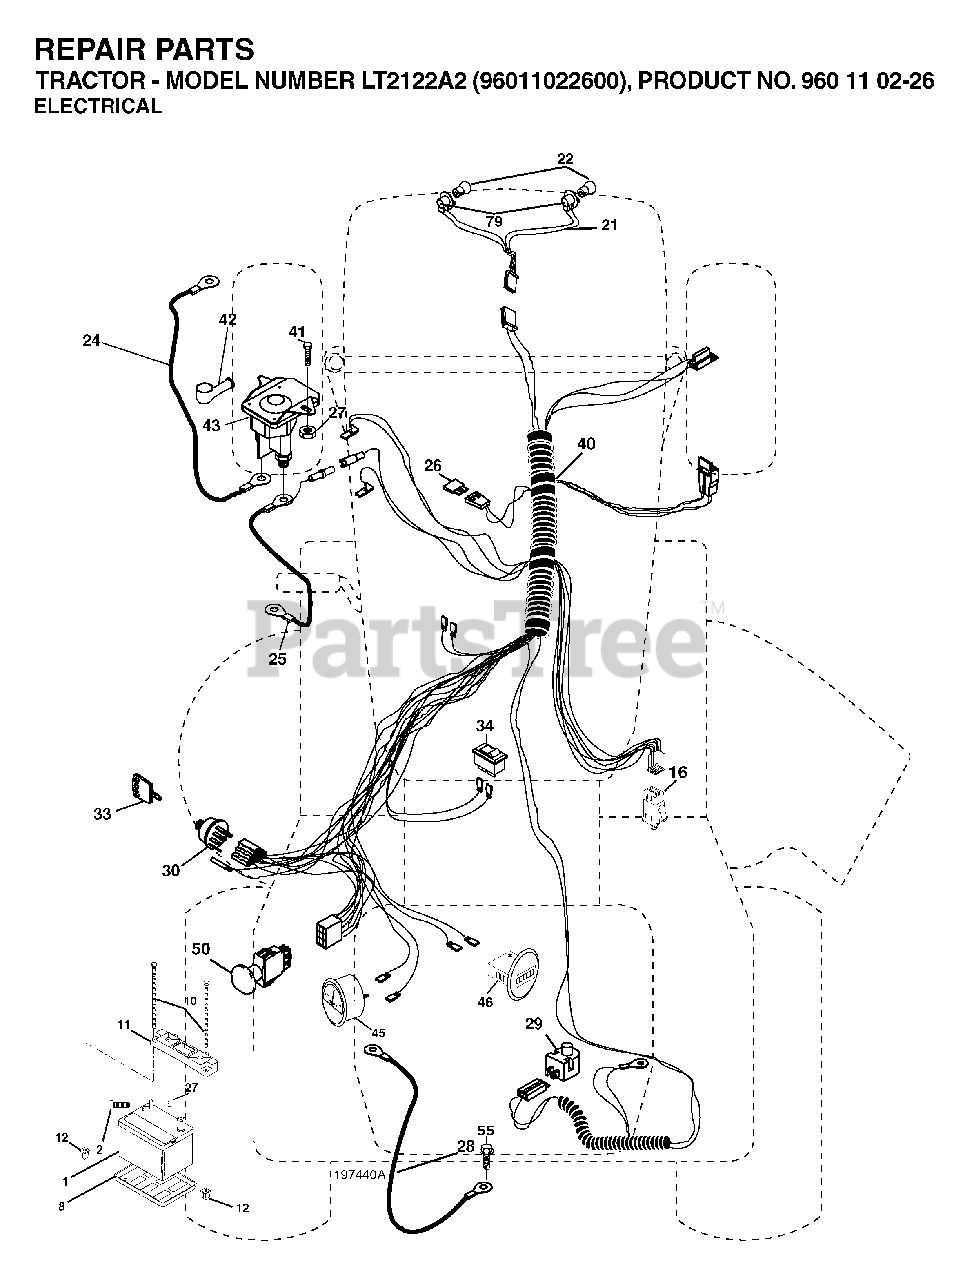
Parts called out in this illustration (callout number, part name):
1	BATTERY 12V .35 AMP
8	BATTERY TRAY T
10	BOLT 1/4-20 X 7.5
11	BATTERY HOLDDOWN
12	NUT, PUSH NYLON 1/4" BATTERY
16	SWITCH INTERLOOK PUSH-IN
21	HARNESS.W/LIGHT SOCKET
22	LIGHTBULB
25	CABLE BATTERY 6 GA 22" W/16W
26	FUSE 20AMP
27	NUT
28	CABLE GROUND 6 GA 21" 90T BLK
29	SWITCH.SEAT.DP W/RAMPS
30	SWITCH.IGN.DELTA.W.LGH.ROS
33	KEY MLD GEN DELTA
34	SWITCH LT
41	SCREW
42	TERMINAL COVER
43	SOLENOID.W/BRASS.PLUNG
46	HOURMETER SNAP-IN
50	PTO SWITCH
79	BULB HOLDER ASM.
